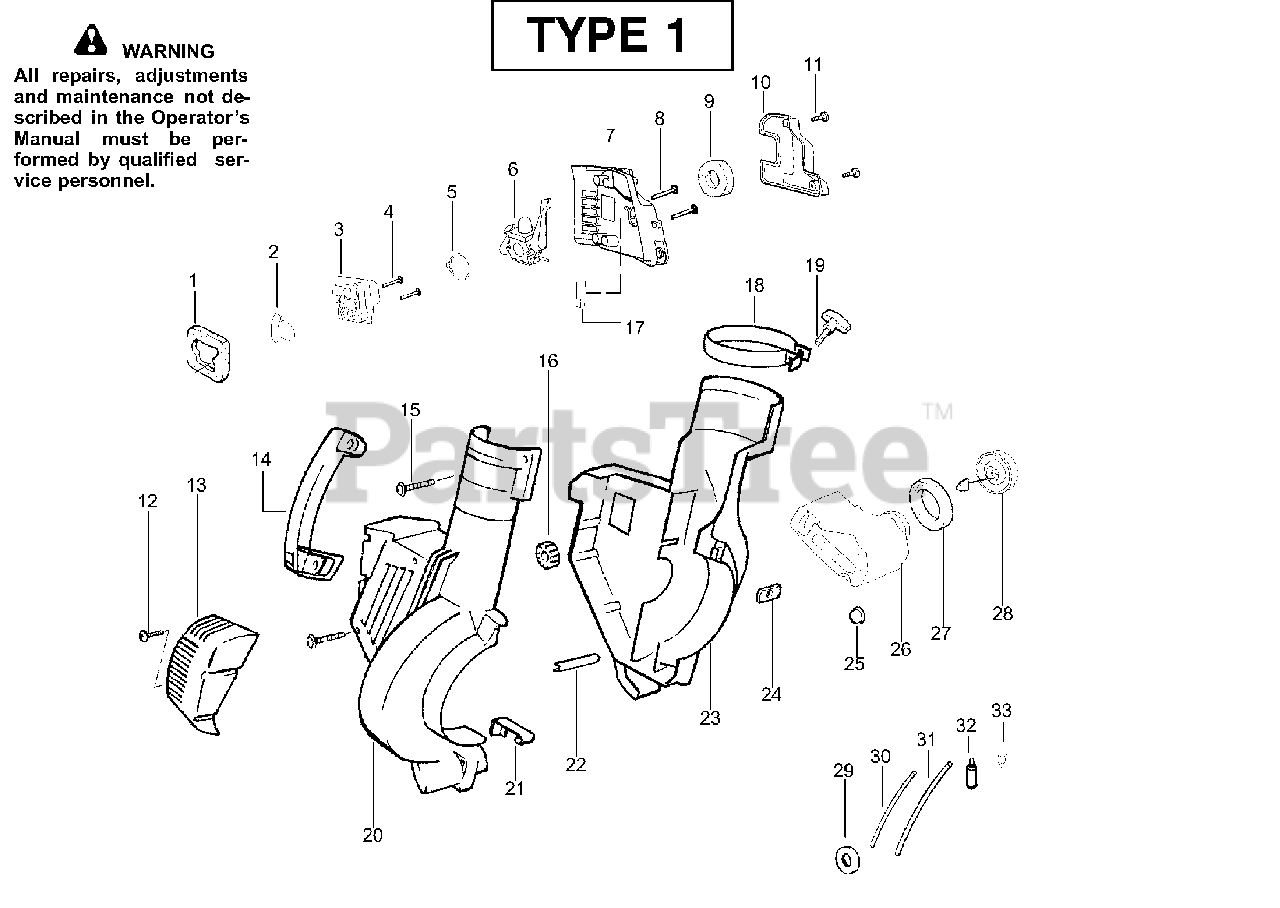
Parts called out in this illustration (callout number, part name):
1	Air Dam (kit)
2	Gasket-Adapter (kit)
3	Carburetor Adaptor
5	Gasket-Carburetor (kit)
6	Kit-Carb Ass'y (C1Q-W11)
8	Screw-Carb.
9	Filter-Air
10	Cover-Air Filter
11	Screw-Air Box Cover
13	Assy-Muffler Cover
16	Isolator
17	Foam 25.4mm (kit)
18	Clamp-Blower Tube
19	Knob-Tube Clamp
20	Housing-Right
21	Spring-Cover Latch
22	Guide-Starter Rope
23	Housing-Left
25	Isolator-Crankcase
26	Assy-Fuel Tank
27	Gasket-Fuel Tank
28	Fuel Cap w/Retainer
29	Grommet-Shroud
30	Kit-Line Carb/Purge
31	Kit-Line Tank/Purge
32	Assy-Fuel Pick-up
33	Grommet-Fuel line (kit)
